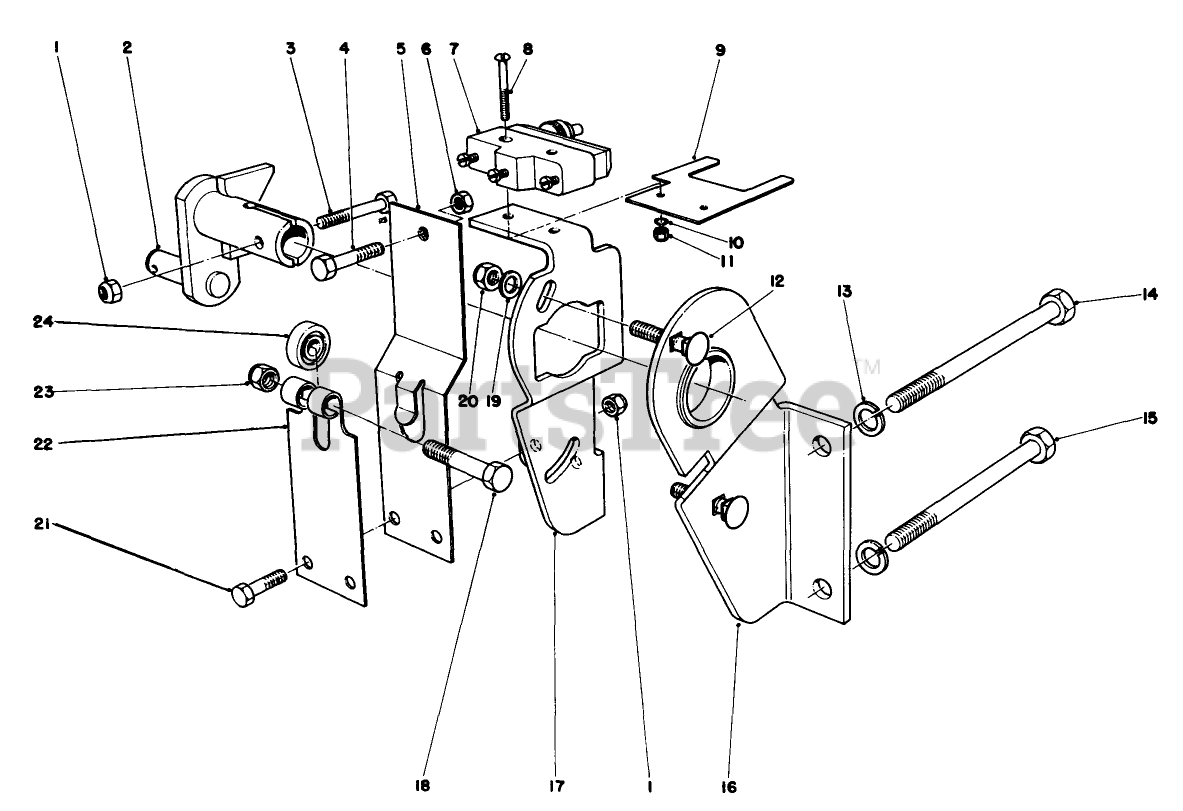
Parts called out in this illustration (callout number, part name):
1	NUT-LOCK, NI
2	Lever-Pump
3	SCREW-HH
4	SCREW-HH
5	EXTENDED LEAF SPRING ASM
6	NUT-HEX
7	Switch
8	SCREW-MACHINE
9	STOP-SPRING, LEAF
10	WASHER-LOCK, INTERNAL
11	NUT-HEX
12	BOLT-CARR
13	WASHER-LOCK
14	SCREW-HH
15	SCREW-HH
16	Bracket-Mounting
17	PLATE-PUMP
18	SCREW-HH
19	WASHER-FLAT
20	NUT-LOCK, NI
21	SCREW-HH
22	SPRING-LEAF
23	NUT-LOCK, NI
24	BEARING-BALL
